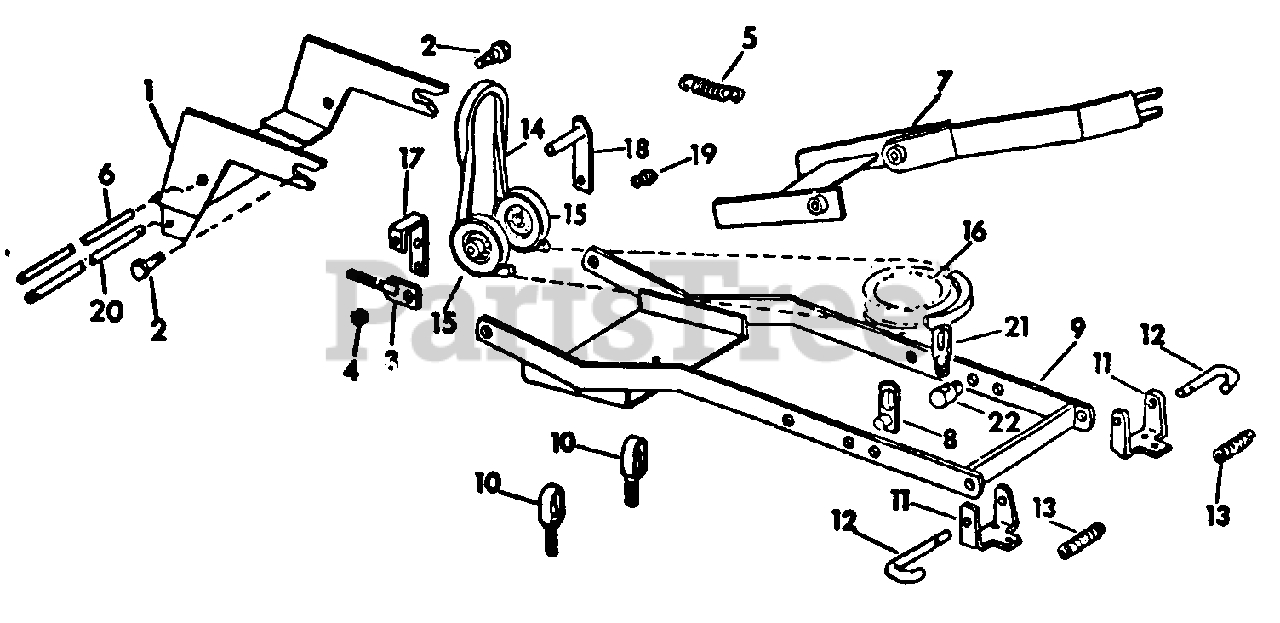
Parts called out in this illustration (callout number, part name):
1	Hanger Assy, Front
2	Bolt, Shoulder
3	Bracket Assy, Idler Adj
4	Spacer, Idler Adj
5	Spring, Mule Drive Extension
6	Shaft, Idler Pivot
7	Frame Assy, Center
8	Link Assy, Lift
9	Frame Assy, Outer Lift
10	Hanger, Mower Support Frt
11	Bracket, Mower Support
12	Pin, Mower Support
13	Spring, Mower Support Pin
14	Belt, Mule Drive -38 & 42 In. Blade
15	Pulley, Drive Belt Idler
16	Pulley, Center -Refer to Main Frame and Knife Units
17	Arm, Idler LH
18	Arm Assy, Idler RH
19	Spacer, Spring
20	Shaft, Frt Hanger
21	Link, Adjustable
22	Block, Adjusting
